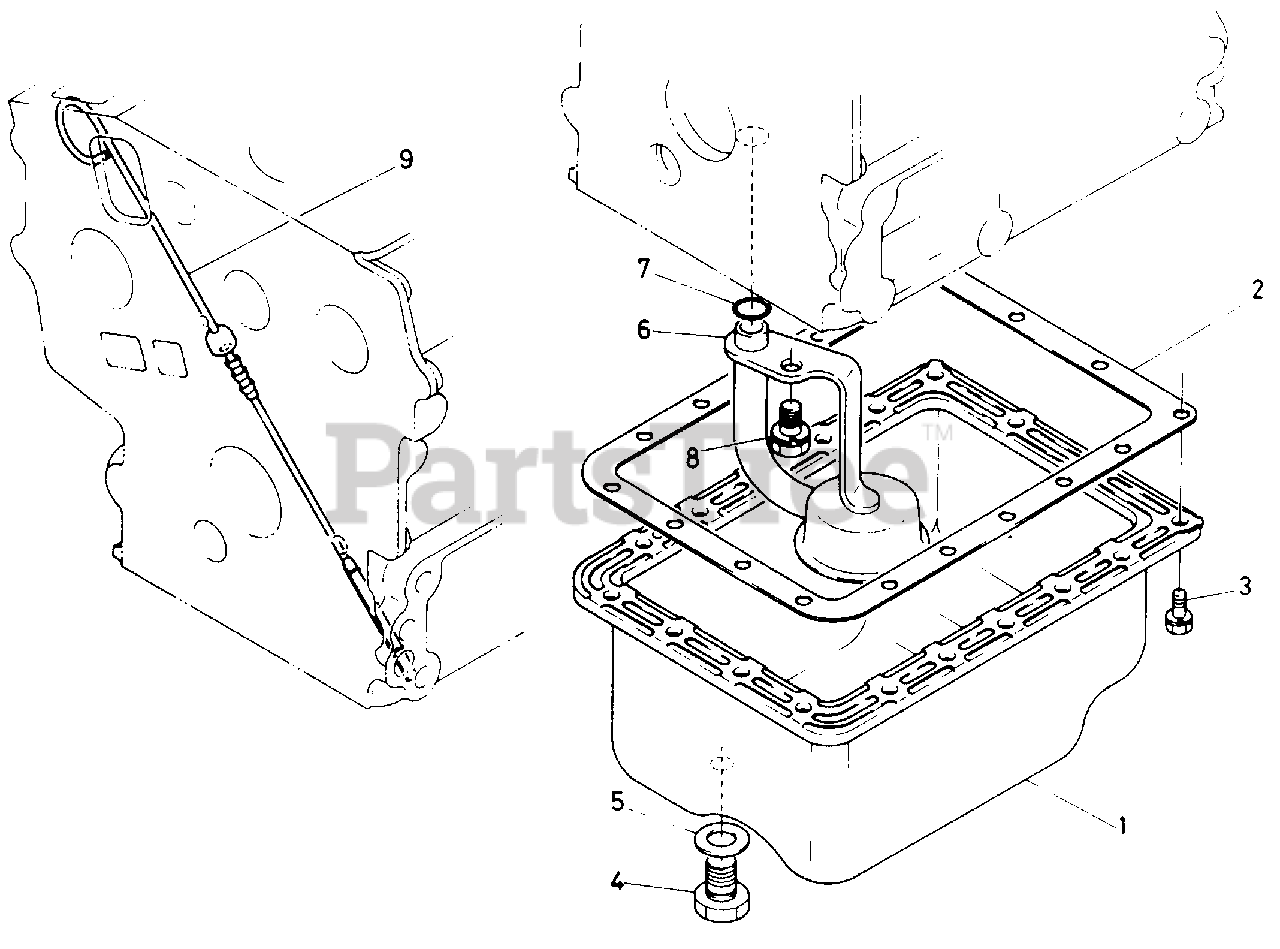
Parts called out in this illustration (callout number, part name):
2	Gasket, Oil Pan
3	Bolt, M6 X 12 Class 8.8
5	Gasket
8	Bolt, M8 X 14 Pln H/Hd Class 8.8
